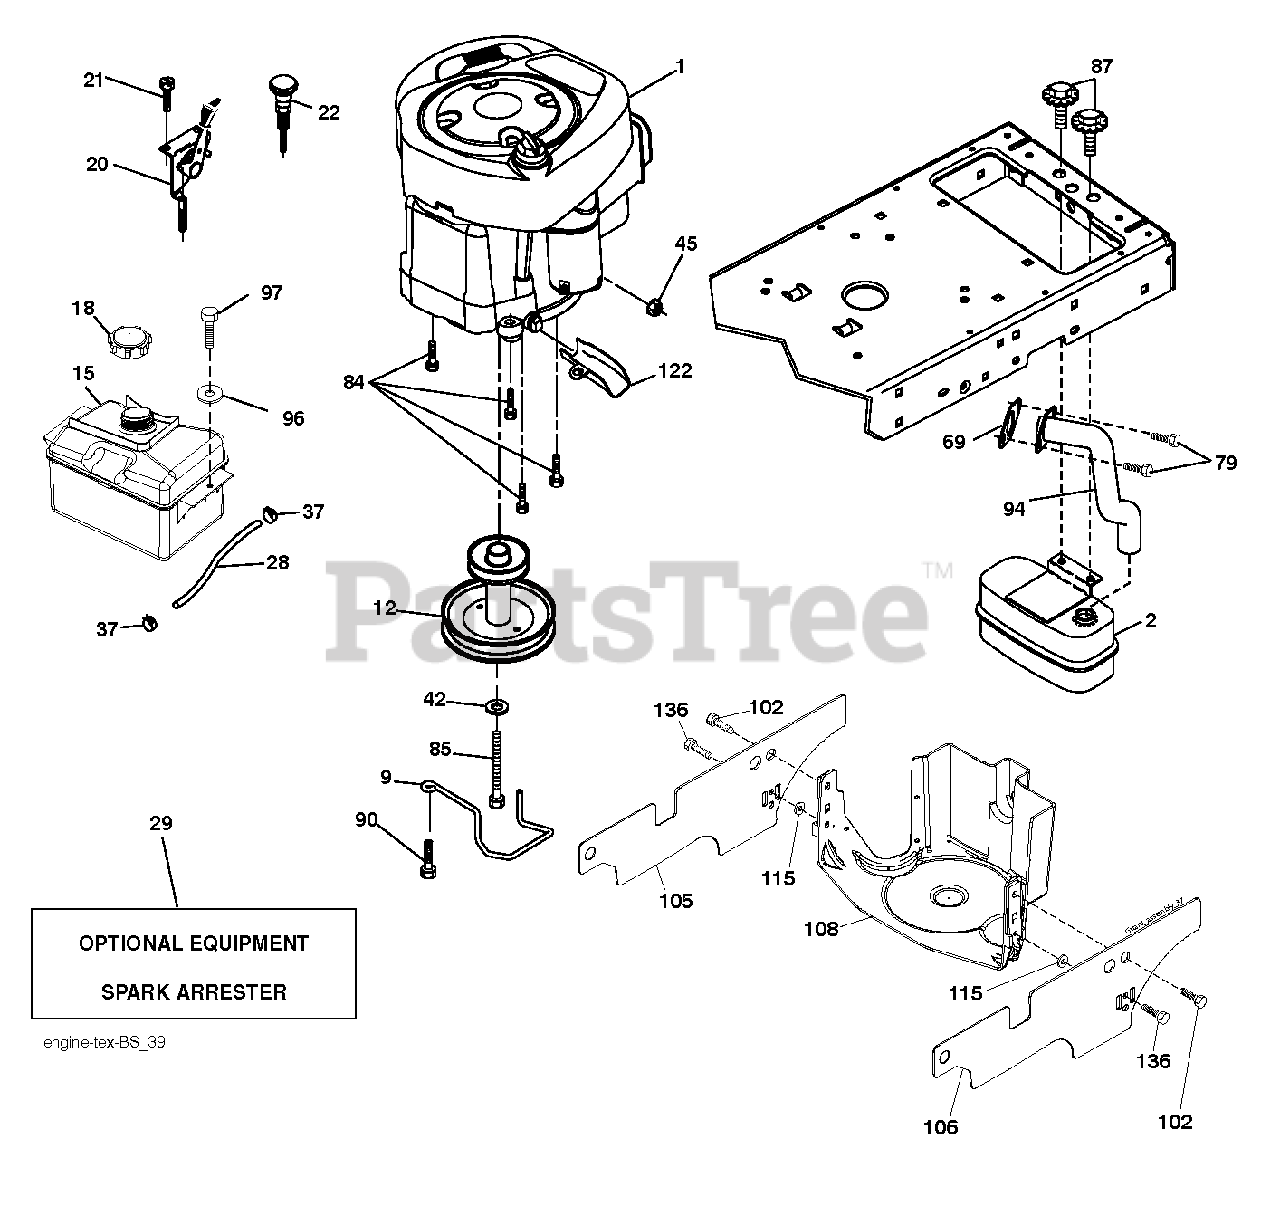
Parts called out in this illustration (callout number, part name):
2	MUFFLER.SINGLE.CYL.KOHL/B&S
9	KEEPER.BELT.ENGINE.3.25
12	PULLEY ENGINE
15	TANK FUEL FRT 1.5 GAL
18	CAP ASM.FUEL.2.25"FR.
20	CONTROL.TH/CK.C.
21	SCREW.#10 X 0.750.BOS THREAD
28	LINE.FUEL.20
29	ARRESTER SPARK (OPTIONAL)
37	HOSE CLAMP
42	LOCKWASHER
45	NUT
69	REPL BY 532 27 22-93
79	SCREW.SOCKET HD.5/16-1
84	SCREW.3/8-16
85	BOLT HEX 7/16-20X4-1/4"
87	BOLT, 5/16-18 X 1 3/4
90	SCREW 3/8-16X1
94	EXHAUST.TUBE.B&S.
96	WASHER
97	SCREW HEXWSHR 1/4-20X3/4
102	SCREW
115	PALNUT 1/4
122	EXTENSION DRAIN OIL
136	SCREW.1/4-20X5/8
